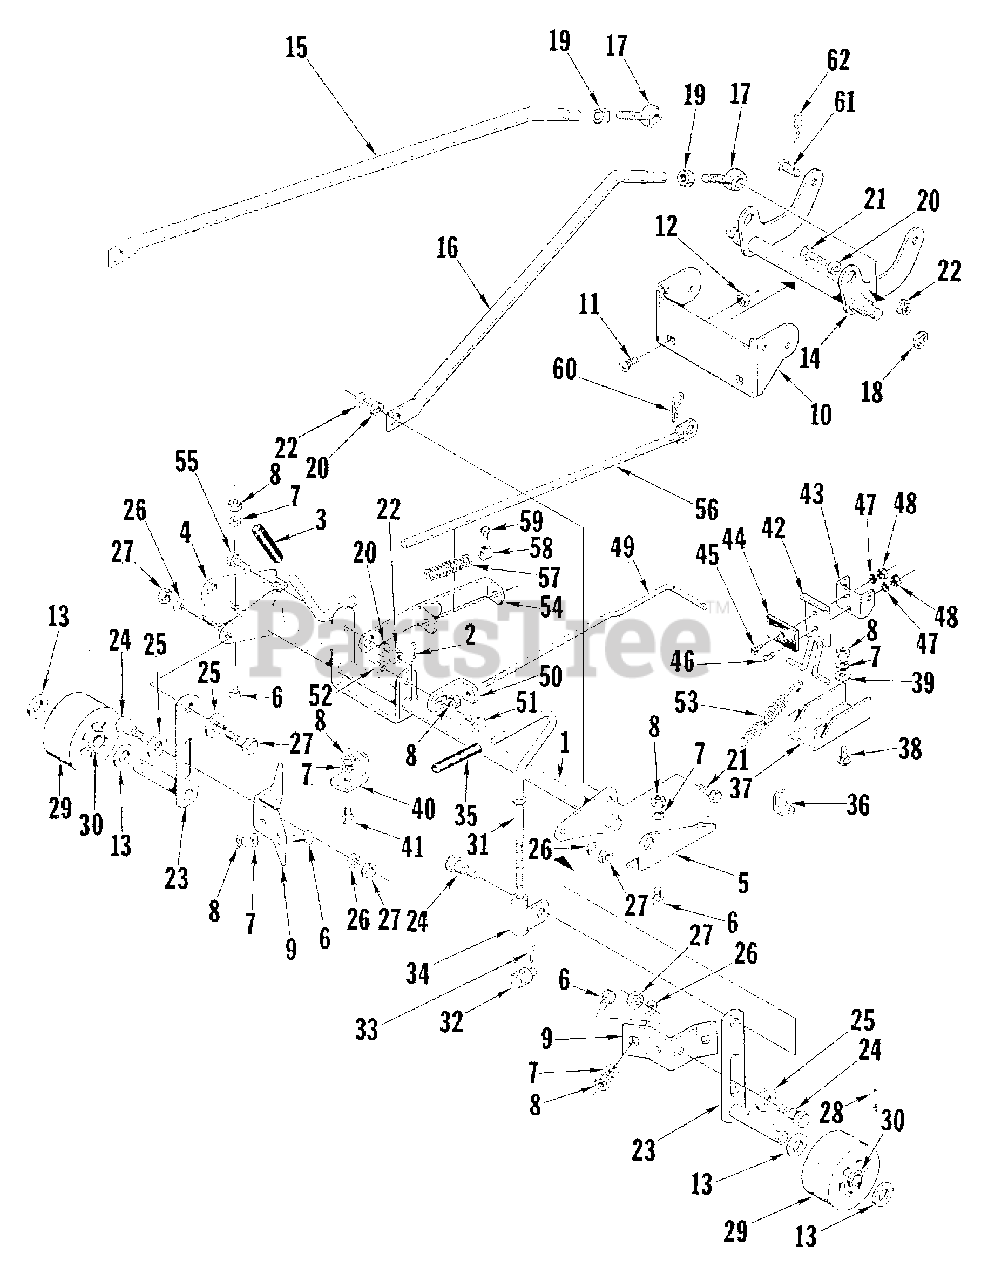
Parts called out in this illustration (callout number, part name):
1	CONTROL ARM ASSEMBLY
3	GRIP, Handle
4	BRACKET, Pivot
5	BRACKET, Pivot
6	BOLT, 5/16-18 x 5/8
7	WASHER, Lock, 5/16
8	NUT, Hex Full, 5/16-18
9	ROLLER BRACKET SUPPORT
10	BRACKET, Front Mower
11	SCREW, Whiz Lock, 5/16-18 x 3/4
12	NUT, Flange, 5/16
14	ROCKER ARM ASSEMBLY
15	ARM, Adjusting
16	ARM, Adjusting
18	RING, Retaining
19	NUT, Hex Jam, 1/2-20
21	SCREW, Hex, 3/8-16 x 1
23	ROLLER SUPPORT ASSEMBLY
24	BOLT, Shoulder
25	WASHER, Plain, 7/16
26	WASHER, Lock, 3/8
27	NUT, Hex Full, 3/8-16
28	PIN, Cotter, 3/16 x 1
29	ROLLER ASSEMBLY
33	PIN, Cotter, 3/32 x 1
36	ANCHOR, Spring
37	BRACKET, Brake Pivot
38	BOLT, Carriage, 5/16-18 x 1
39	WASHER, Plain, 5/16
41	SCREW, Hex, 5/16-18 x 5/8
42	BRAKE SUPPORT ASSEMBLY
43	ANCHOR, Brake Rod
44	SHEAVE, Brake
45	SCREW, Slotted, 10-24 x 5/8
46	SCREW, 10-24 x 1/2
48	NUT, Hex, 10-24
50	BRACKET, Brake Adjusting
51	BOLT, Shoulder
52	NUT, Hex Full Lock, 3/8-16
55	SCREW, Hex, 3/8-16 x 1
59	SCREW, Set, 1/4-20 x 3/8
60	CLIP, Spring
62	CLIP, Spring
